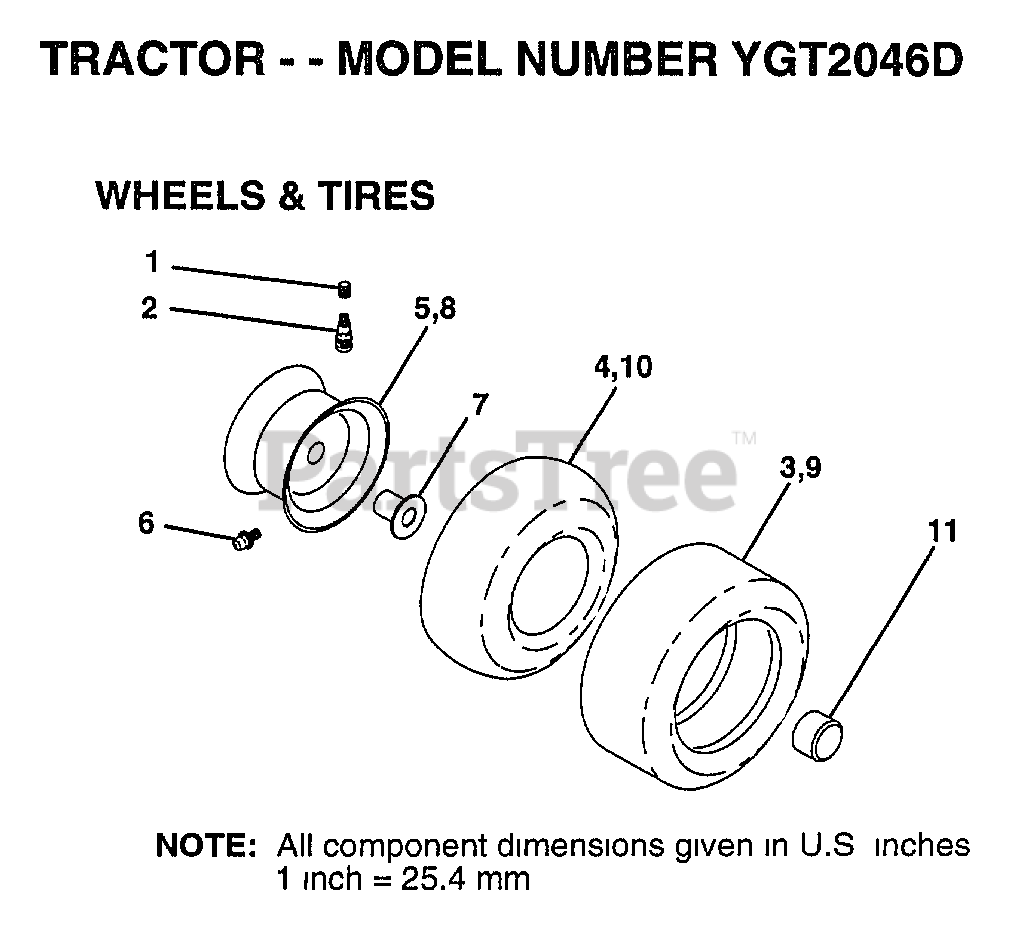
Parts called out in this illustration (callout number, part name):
1	VALVE CAP
2	VALVE STEM LT
4	TUBE.5.3/4.5/6
5	"RIM ASM 8"" FRT"
6	FITTING LT
7	"FLANGE, BEARING"
8	RIM.REAR.
9	TIRE.R.23X9.5-12
10	TUBE.23X8/10-12
11	HUB CAP
